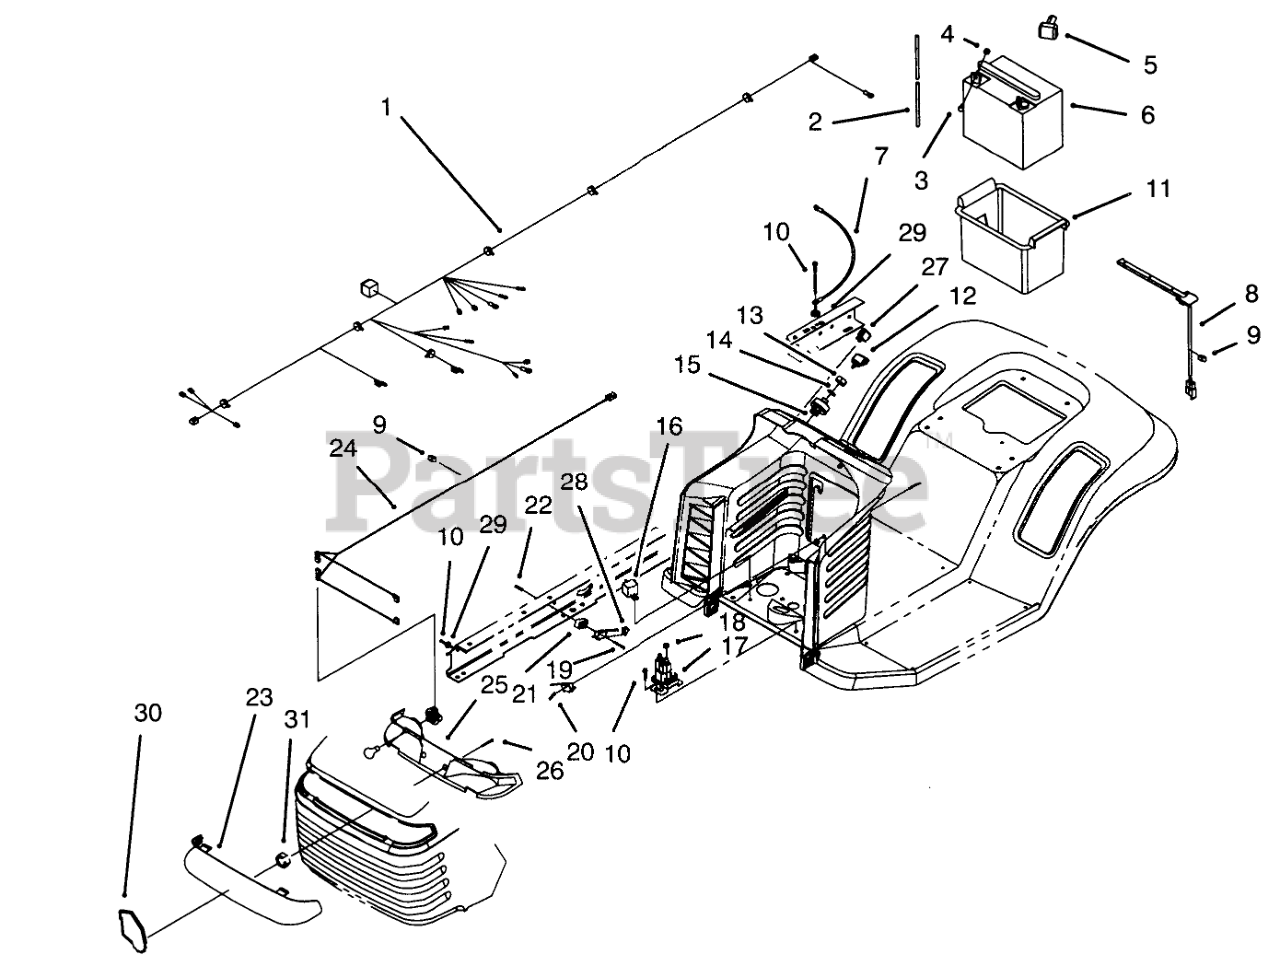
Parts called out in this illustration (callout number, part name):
1	Harness-Wire
2	TUBE-BATT DRAIN/80-2600
3	SCREW-HH
4	NUT-WING
5	BOOT-TERMINAL
6	Battery
7	WIRE ASM
8	SWITCH-SEAT
9	CLIP-RETAINER, WIRE
10	SCREW-HWH
11	BOX-BATTERY
12	KEY-IGNITION
13	NUT-HH
14	WASHER-TOOTH, INTERNAL
15	Key Switch ASM
16	RELAY
17	Solenoid
18	NUT-KEPS
19	Screw
20	SWITCH-MICRO
21	SPACER
22	NUT-SPEED
23	LENS-HEADLIGHT
24	HARNESS-WIRE, LIGHTS
25	HEADLIGHT REFLECTOR ASM
27	SWITCH-ROCKER
28	PLUNGER-SEAL
29	WASHER-LOCK/EXT
30	EMBLEM-GRILLE WHEELHORSE
